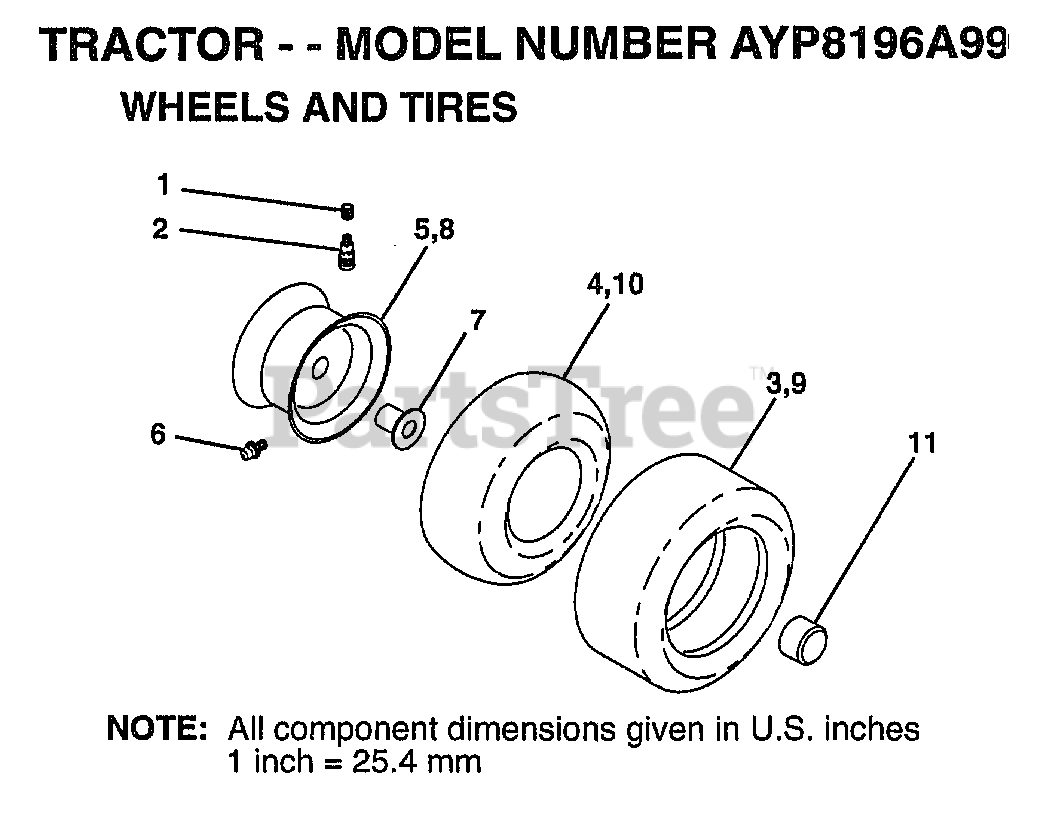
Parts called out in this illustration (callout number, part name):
1	VALVE CAP
2	VALVE STEM LT
4	TUBE.5.3/4.5/6
5	"RIM ASM 8"" FRT"
6	FITTING LT
7	"FLANGE, BEARING"
8	RIM.REAR.
10	TUBE.23X8/10-12
11	HUB CAP
